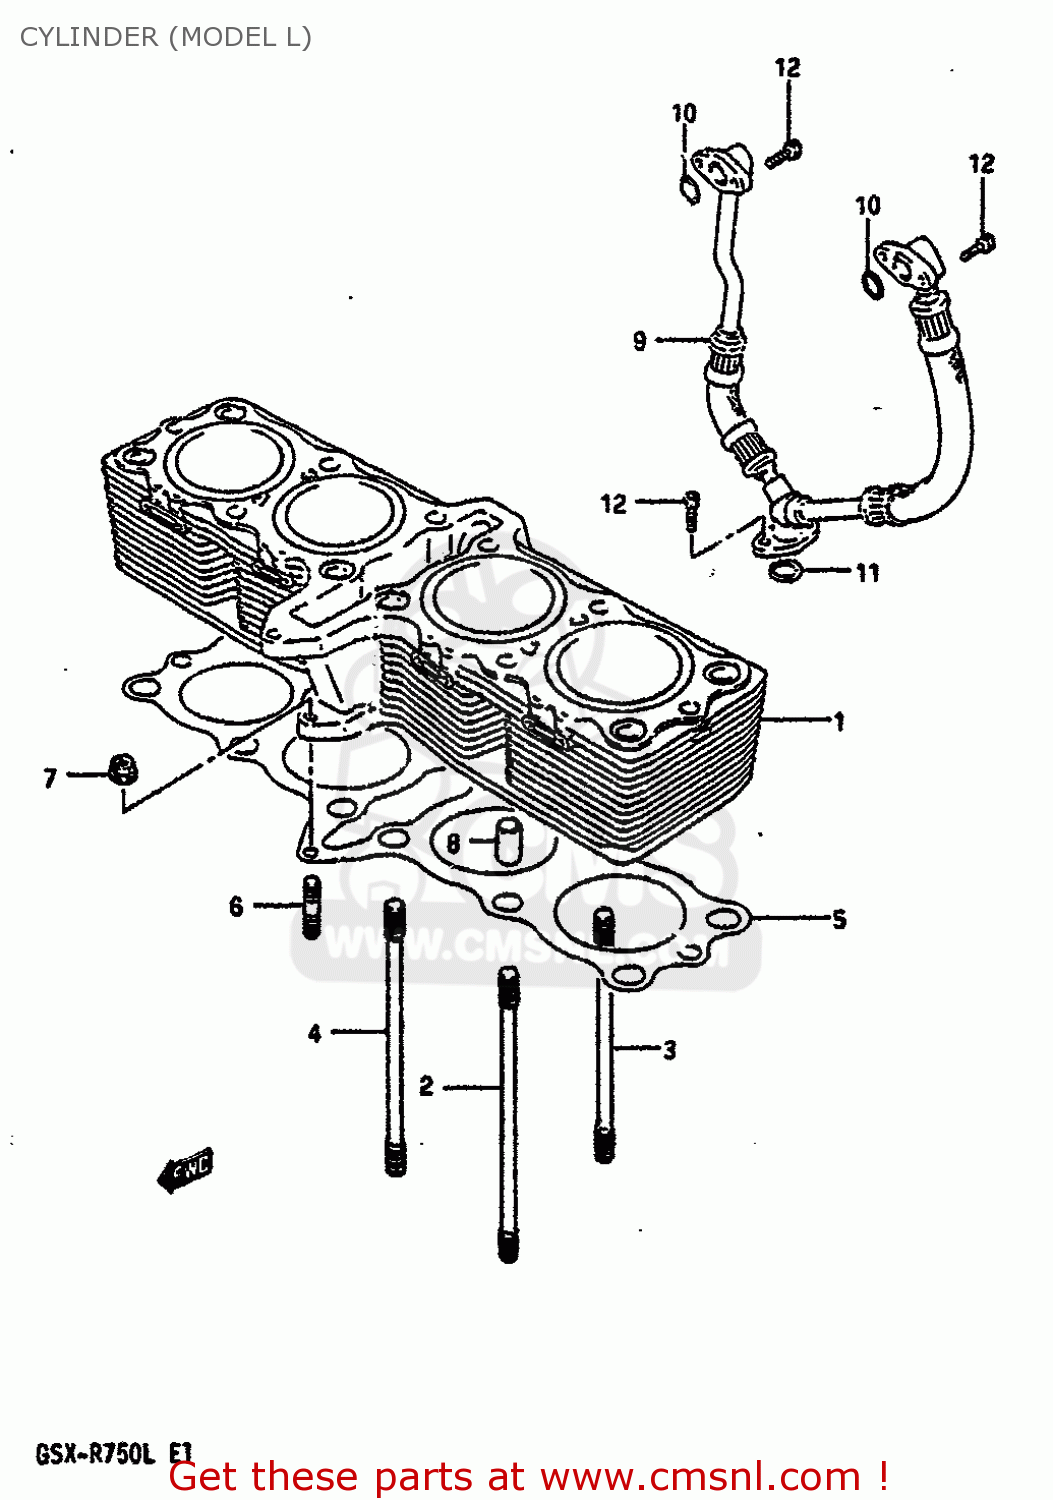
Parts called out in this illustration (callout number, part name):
1	CYLINDER
2	STUD BOLT (L:150)
3	BOLT,STUD
4	STUD
5	GASKET,CYLINDER (NAS)
6	STUD BOLT L:20
7	NUT 6MM
8	PIN
9	HOSE
10	O RING(D:2.5,ID:13.8)
11	O RING(D:2.4,ID:15.8)
12	BOLT
